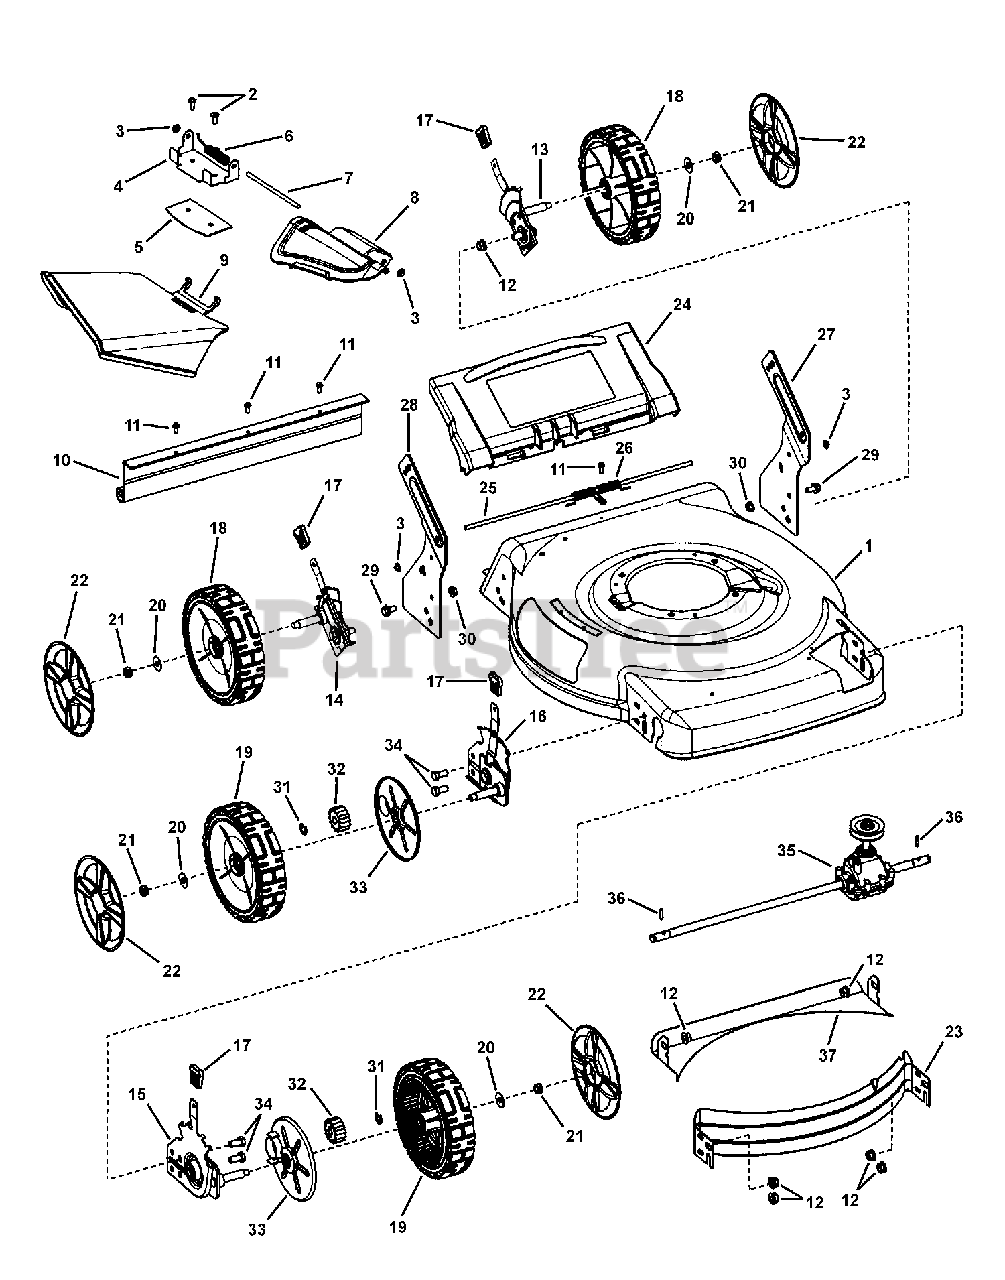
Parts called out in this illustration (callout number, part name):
1	DECK, 22" Walk, 3-N-1
2	SCREW, 1/4-20 x 11/16" Pan Head Self-Tap (Torx)
3	PUSHNUT, 1/4"
4	BRACKET, Chute
5	PLATE, Mulch, 22" RB Scott's
6	SPRING, Chute (Torsion)
7	ROD, Pivot (1/4" Dia. x 5.55")
8	COVER, Mulch, Plastic, Black
9	SIDE CHUTE, Plastic, Black
10	GUARD, Rear
11	SCREW, #10-24 x 1/2" Hex Washer Self-Tap (Sems)
12	NUT, 3/8-16 Hex Flange Lock, YZ
13	ASSEMBLY, Height-Of-Cut, Left Rear, 22" WBM
14	ASSEMBLY, Height-Of-Cut, Right Rear, 22" WBM
15	ASSEMBLY, HOC, Left Front, 22" WBM, Propelled
16	ASSEMBLY, HOC, Right Front, 22" WBM, Propelled
17	GRIP, Height Latch - Black (1.3" Wide)
18	ASSEMBLY, Wheel & Bearing, 8 x 2 Idle, DW Tread
19	ASSEMBLY, Drive Wheel & Bearing, 8 x 2, DW Tread
20	WASHER, 1" O.D. x .387 I.D. Flat
21	NUT, 3/8-16 Hex Center Lock, YZ
22	HUBCAP, Black
23	BAFFLE, Front, 22" WBM
24	DOOR, 22" Rear
25	ROD, Pivot, Rear Door (1/4" Dia. X 17-1/2")
26	SPRING, Torsion, Rear Door, 22" WBM
27	BRACKET, Lower Handle, LH 22" WBM
28	BRACKET, Lower Handle, RH 22" WBM
29	BOLT, 5/16-18 x 5/8" Hex Flange Lock, YZ
30	NUT, 5/16-18 Flange Lock, YZ
31	RING, External Retaining
32	GEAR, Pinion, 22" WBM, Front Wheel Drive
33	DUST SHIELD, Forward, 22" WBM
34	SCREW, 3/8-16 x 3/4" Hex Head Cap, GR 5, YZ
35	TRANSMISSION, Rocker 22" WBM, VS
36	DRIVE PIN, 22" WBM, Front Wheel Drive
37	BAFFLE, Rear, 22" Deck
